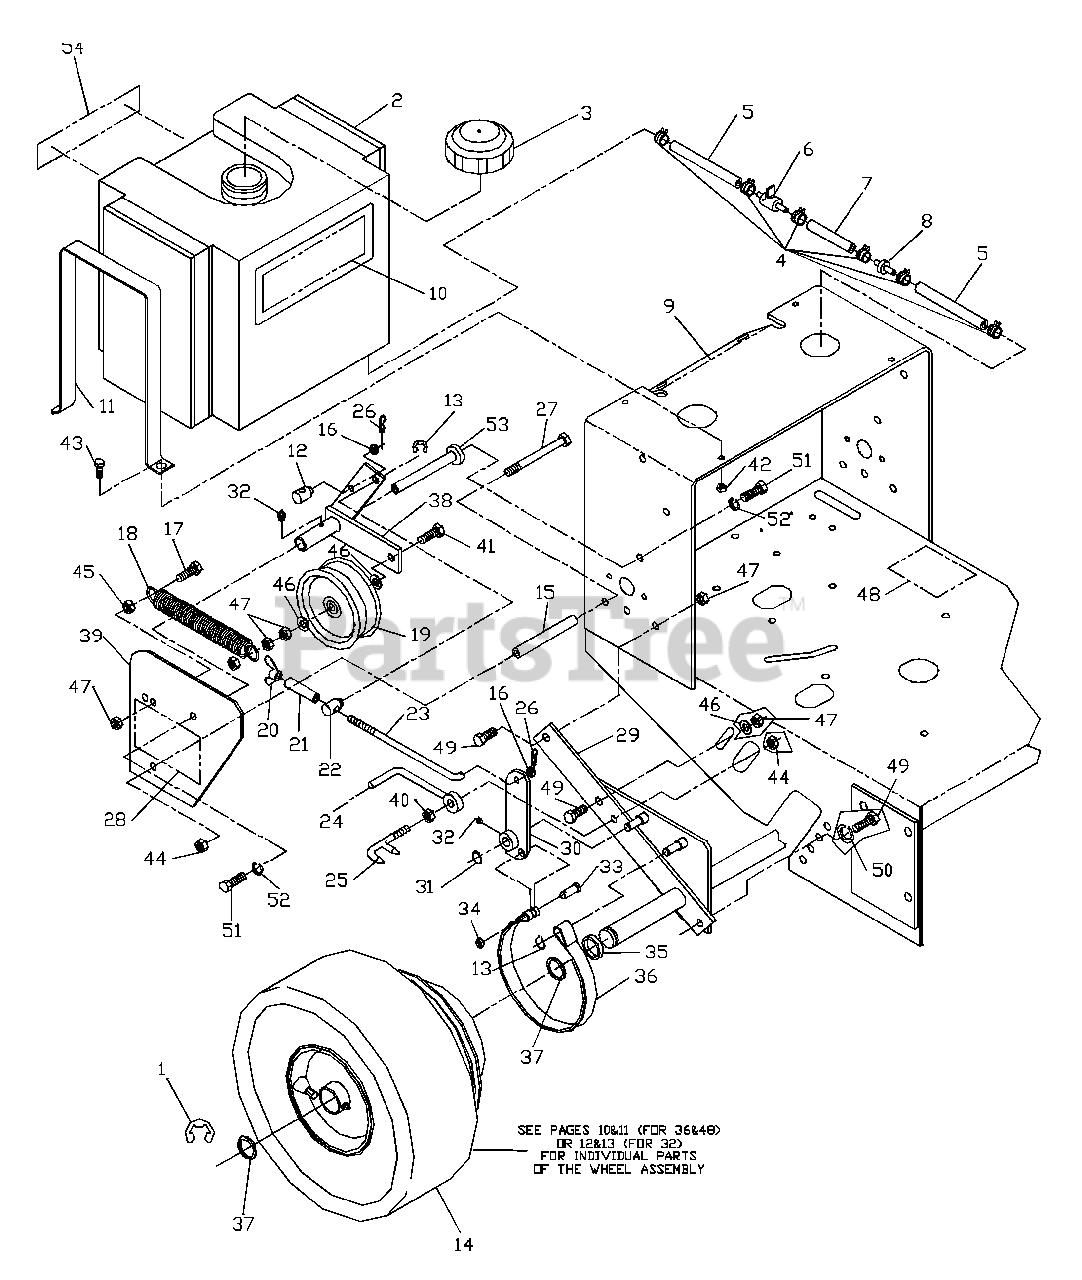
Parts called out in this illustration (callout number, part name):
1	1" E-RING
4	HOSE CLAMP (Kawasaki)
4	HOSE CLAMP (Kohler)
5	10" GAS LINE (Kawasaki)
5	10" GAS LINE (Kohler)
6	FUEL VALVE
7	3 1/2" GAS LINE (Kaw. only)
7	14" GAS LINE (Kohler)
8	FUEL FILTER (Kaw. only)
9	REAR DECK W/DECALS
10	DECAL, W3212
10	DECAL, W3213
10	DECAL, W3612
10	DECAL, W3613
10	DECAL, W3614
10	DECAL, W4814
10	DECAL, W4815
11	TANK STRAPS
12	SWIVEL(SHORT)
13	3/8" E-RING
14	WHEEL ASM.(36&48)
14	WHEEL ASM.(32)
15	LONG SPACER
16	5/16 FW STD
17	HCS 3/8C X 1 1/4
19	IDLER PULLEY
20	5/16C NYLOC WINGNUT
24	BELT GUIDE
25	SCRAPER(36 & 48)
25	SCRAPER(32)
26	#2 HAIRPIN
27	HCS 5/16C X 5
28	DECAL, SMALL CROWN
29	AXLE WLDMT(36&48)
29	AXLE WLDMT(32)
30	RT. BRAKE ARM
30	LT. BRAKE ARM
31	1/2' E-RING
32	ZERK 1/4-28 STRHT
33	CLEVIS PIN
34	BOLT RETAINER 3/8
36	BRAKE BAND
37	MACH. BUSHING
38	IDLER PLATE, LT
38	IDLER PLATE, RT
40	HFLN 5/16C
41	3/8C X 3 TAPBOLT
43	HCS 1/4C X 1
46	FW 3/8 STD
47	HLN 3/8C CENTER P.
48	DECAL, PROP. 65
49	HCS 3/8C X 1
50	SLW 3/8 STD
51	HCS 5/16C X 1
52	SLW 5/16 STD
53	SHOULDER PIVOT TUBE
54	DECAL, HUSQVARNA
